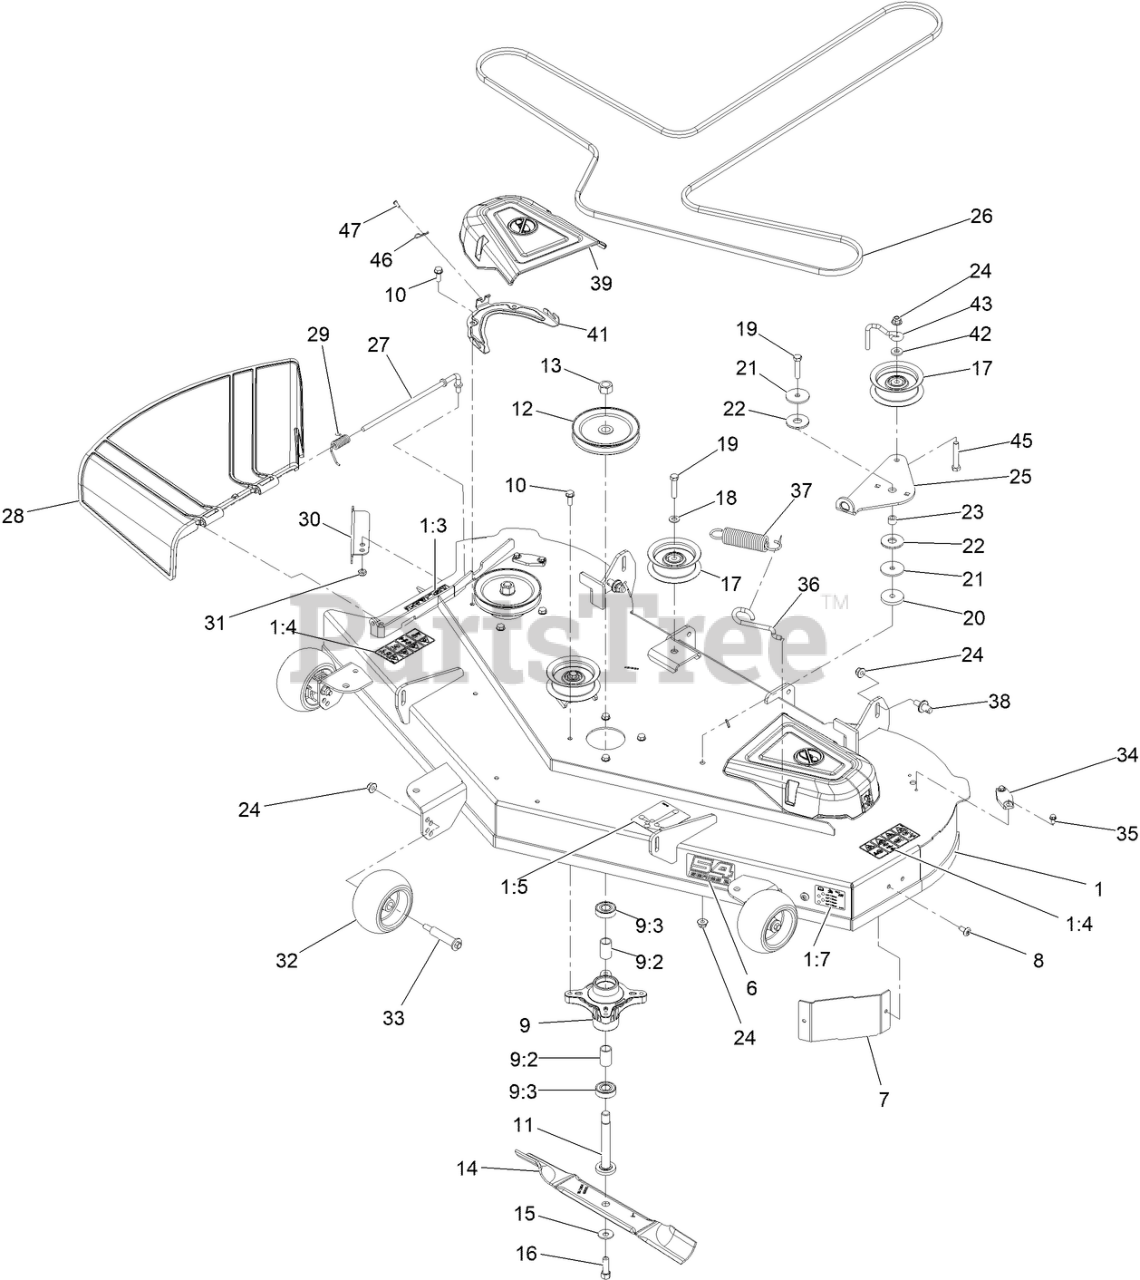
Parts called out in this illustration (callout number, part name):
1	DECK ASM-54 4PT
1:3	DECAL-DANGER
1:4	DECAL-DANGER, DECK
1:5	DECAL-ROUTING, BELT
1:7	DECAL-SCALP, ANTI
6	DECAL-54 SERIES 2
7	BAFFLE-CORNER
9	SPINDLE ASM
9:3	BEARING-BALL
10	SCREW-TAPTITE
11	SHAFT-SPINDLE
12	PULLEY ASM
13	NUT-HEX
14	BLADE-HI LIFT
15	WASHER-BELLEVILLE
16	SCREW-HH
17	PULLEY-IDLER, FLAT
18	WASHER-FLAT
19	SCREW-HH
20	WASHER-PLAIN
21	WASHER-REBOUND
22	WASHER-FRICTION, COMPOSIT
24	NUT-HF, NI
25	Arm-Idler
26	BELT-V
27	ROD-PIVOT
28	DEFLECTOR-DISCHARGE
29	SPRING-TORSION
30	BAFFLE-CUTOFF
32	ROLLER-SCALP, ANTI
33	BOLT-SHOULDER
34	COVER-WASHOUT PORT
35	SCREW-HWH
36	Hook-Return Spring
37	SPRING-EXTENSION
38	PIN-DECK
39	COVER-BELT
41	BRACKET-COVER, BELT
42	SPACER-HUB, BLOWER
43	Belt Guide - Idler
45	SCREW-HH
46	PIN-HAIR
